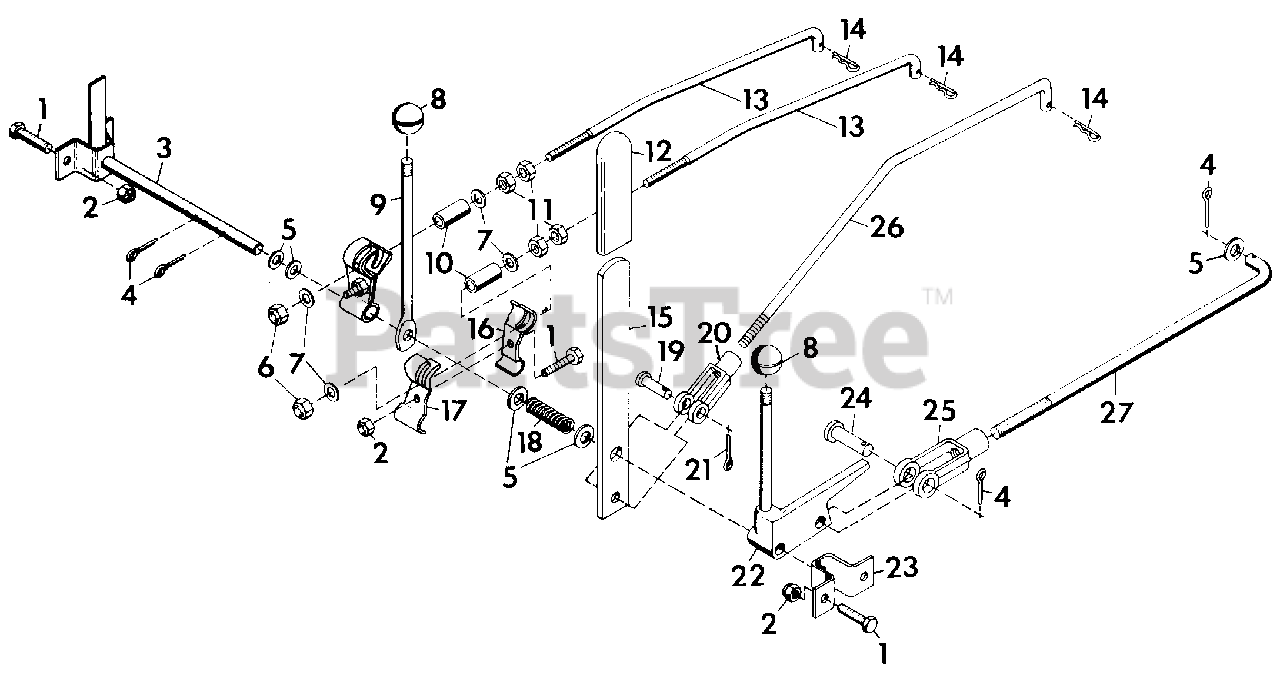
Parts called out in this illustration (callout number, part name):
1	BOLT, HEX 5/16-18X.75
2	NUT, LOCK 5/16-18
3	WELDMENT, CROSS SHAFT
4	PIN, COTTER .12X1.0
5	WASHER, FLAT .531X1.06X.095
6	NUT, LOCK 3/8-16
7	WASHER, FLAT .438X1.00X.083
8	KNOB, CONTROL
9	LEVER, SHIFT
10	BUSHING, .400X.500X1.65
11	NUT, JAM 3/8-16
12	GRIP, HANDLE
13	ROD, SHIFT
14	PIN, COTTER HAIR
15	LEVER, HI-LO SHIFT
16	ARM, SHIFTER R.H.
17	ARM, SHIFTER L.H.
18	SPRING, COMPRESSION
19	PIN, CLEVIS .375X.948
20	CLEVIS, 3/8-24 ADJUSTABLE
21	PIN, COTTER .09X.75
22	ASSEMBLY, PTO CONTROL
23	BRACKET, CROSS SHAFT
24	PIN, CLEVIS .500X1.213
25	YOKE, 1/2-20 ADJUSTABLE
26	ROD, 2-SPEED
27	ROD, PTO
